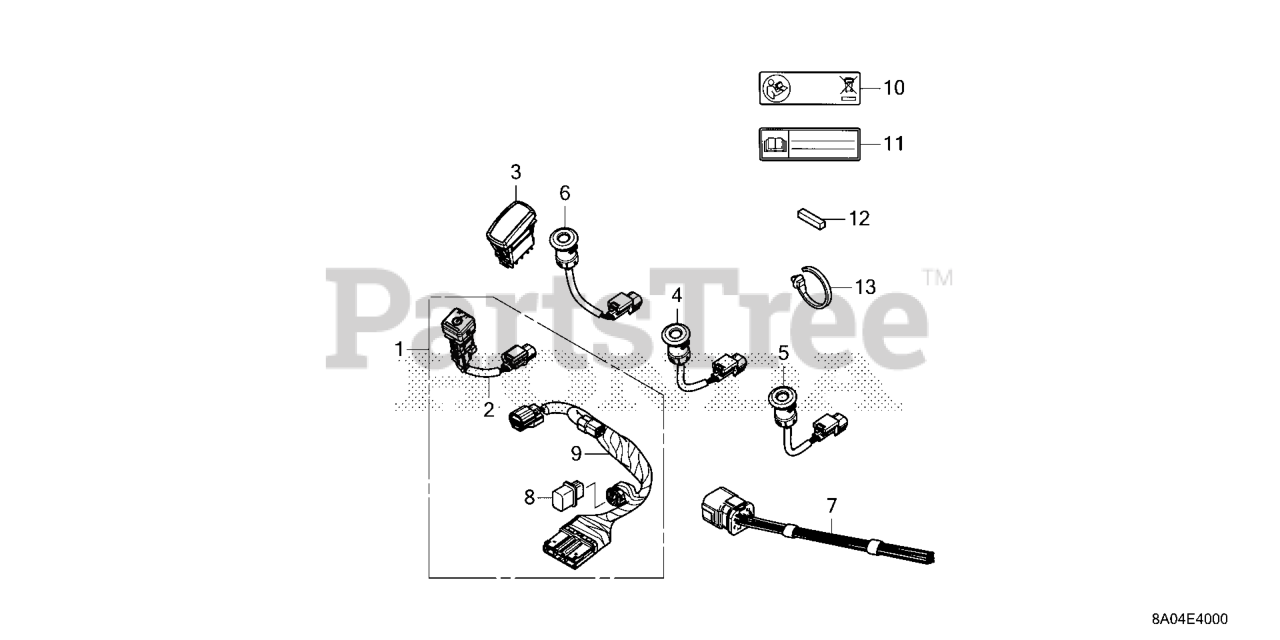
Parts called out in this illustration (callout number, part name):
1	CORD KIT, PC
2	SWITCH ASSY., POWER
3	SWITCH ASSY., START
4	LAMP, INDICATOR
5	LAMP, INDICATOR
6	LAMP, INDICATOR
8	TERMINATOR ASSY.
9	WIRE, PC
12	KEY (5X5X33)
13	CLIP, HARNESS BAND (145MM) (BLACK)
